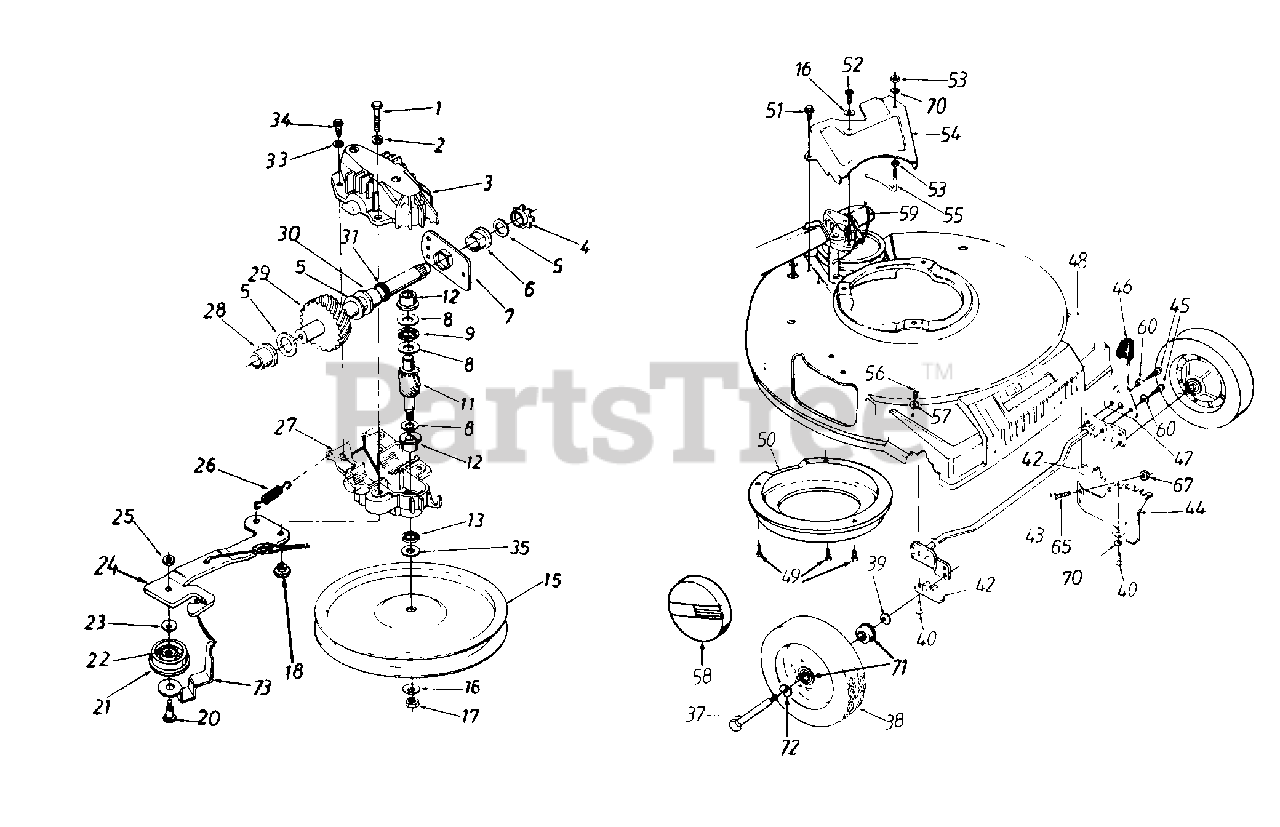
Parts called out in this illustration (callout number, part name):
1	Hex Patch Bolt 1/4-20 x 1.25"
2	L-Wash. 1/4" I.D.
3	Upper Hsg. Half
4	#48 Sprocket 7T x 1/2 Pitch
5	Fl-Wash. 5/8" I.D. x .030
6	Hex Flange Brg. .631" I.D.
8	Thrust Wash. .382" I.D. x .70" O.D
9	Thrust Bearing .375" I.D. x .812" O.D.
11	11 Tooth Pinion Shafts
12	Flange Bearing
15	Fl-Pulley 5.06" O.D.
16	Bell-Wash. .265" I.D. x.75"
17	Hex L-Nut 1/4-28 L.H. Thd.
18	Shld. Spacer .375" Dia. x .170
20	Shld. Bolt .375" Dia. x .40"
21	Fl-Idler Plastic 1.50" Dia.
22	Needle Brg. .375" x .31
24	Idler Brk't. Ass'y.
25	Hex Patch L-Nut 1/4-28 Thd.
26	Extension Spring 1.12" Lg.
27	Lower Hsg. Half
28	Flange Bearing .566 Dia.
29	Shaft Ass'y.
30	Flange Bearing .629 Dia.
31	Oil Seal .625 Dia.
33	L-Wash. #10 I.D.
34	Hex B-Tap Scr. #10 x.62"
35	Hex Washer 26" x .88"
37	Front Axle Bolt
38	Wheel Ass'y Comp.
39	Bell-Wash 380" I.D. x .88
40	Hex Wash Hd. Scr 1/4 x 1" Lg.
42	Block Bushing
43	Axle Ass'y
44	Height Adj. Bracket
45	Hex TT-Tap Scr 1/4-20 x .38"
46	Knob
47	Spring Lever
48	Plastic Front End
49	Hex B-Tap Scr. 1/4" x .38"
50	Belt Cover
51	Hex Wash. Hd. TT-Scr. 1/4-20
52	Hex Wash Hd B-Tap Scr 1/4 x .62" (Spec.)
53	Hex Nut 1/4-20 Thd.
56	Torx Truss Hd. Scr. 5/16 x .75"
57	Bell-Wash 345" I.D. x .88"
58	Hub Cap
59	S.P. Cable
60	External L-Wash 1/4" I.D.
65	Carr. Bolt 1/4-20 x .5" Lg.
67	Hex Flange L-Nut 1/4-20 Thd.
70	L-Wash 1/4" I.D.
71	Wheel Bearing
72	Wave Washer
73	Belt Guard
